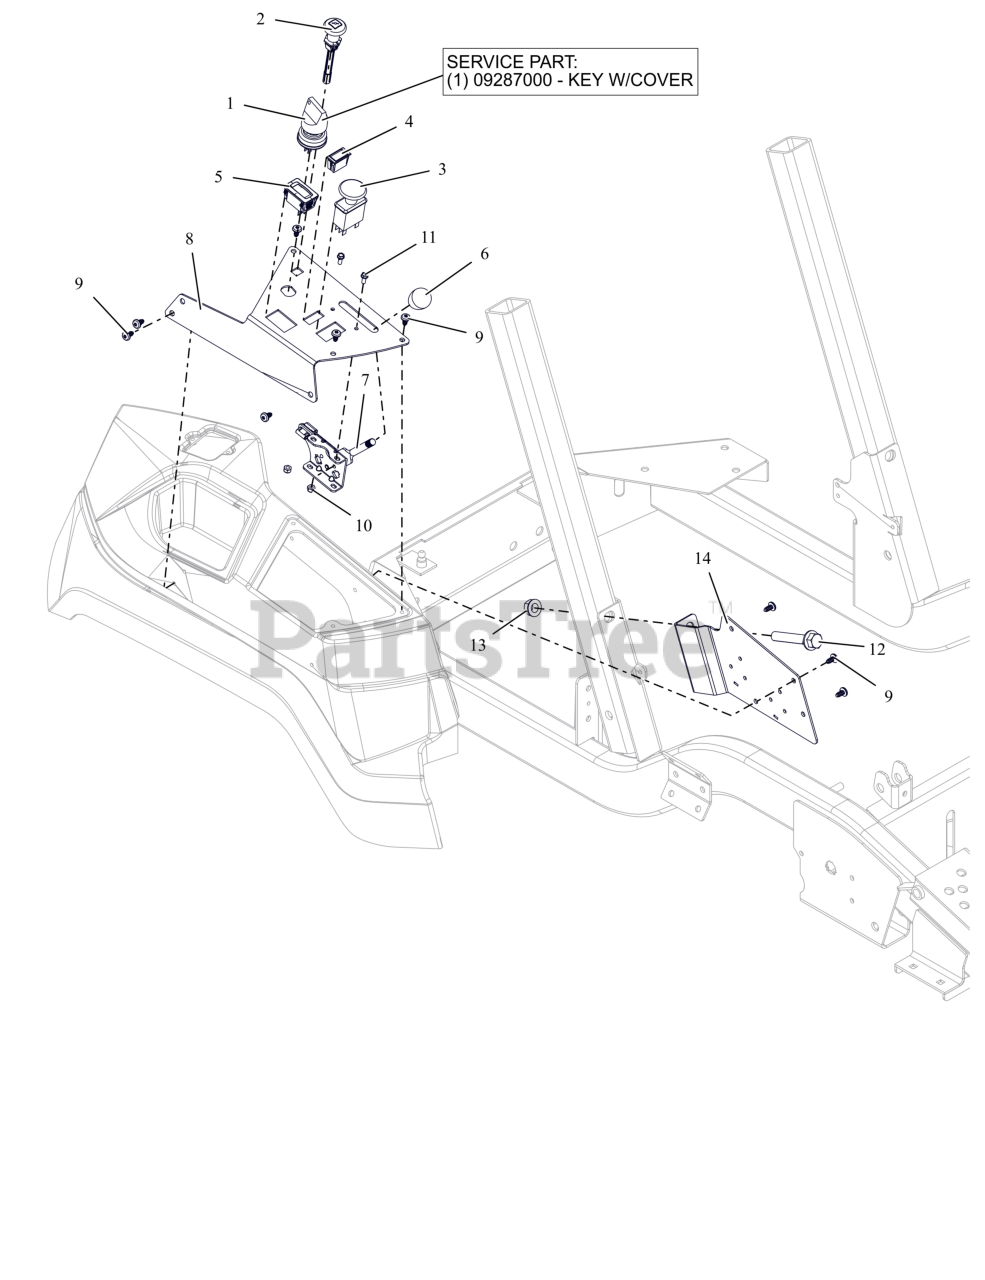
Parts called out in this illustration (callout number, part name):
1	SWITCH, IGNITION
1	KEY, W/ SHIELD
2	CABLE - CHOKE, SNAP-IN
3	SWITCH, CLUTCH
4	SWITCH,BLANK
5	HOUR METER
6	KNOB-CONTROL-BLACK .38-16X.50
7	CABLE, PRO THROTTLE CONTROL
8	PLATE, APEX CONTROL PANEL
9	SCR-PAN .25-15X.50 6L H/LZB500
10	NUT-LK-NYL #10-24 G2 ZCC
11	BLT, HWH #10-24X.50 ZCC
12	BLT- HEX-FLG .50-13X3.00 G5 ZC
13	NUT-LK-CTR-FLG .500-13 GG ZCC
14	BRKT, FENDER/RELAY MOUNTING
